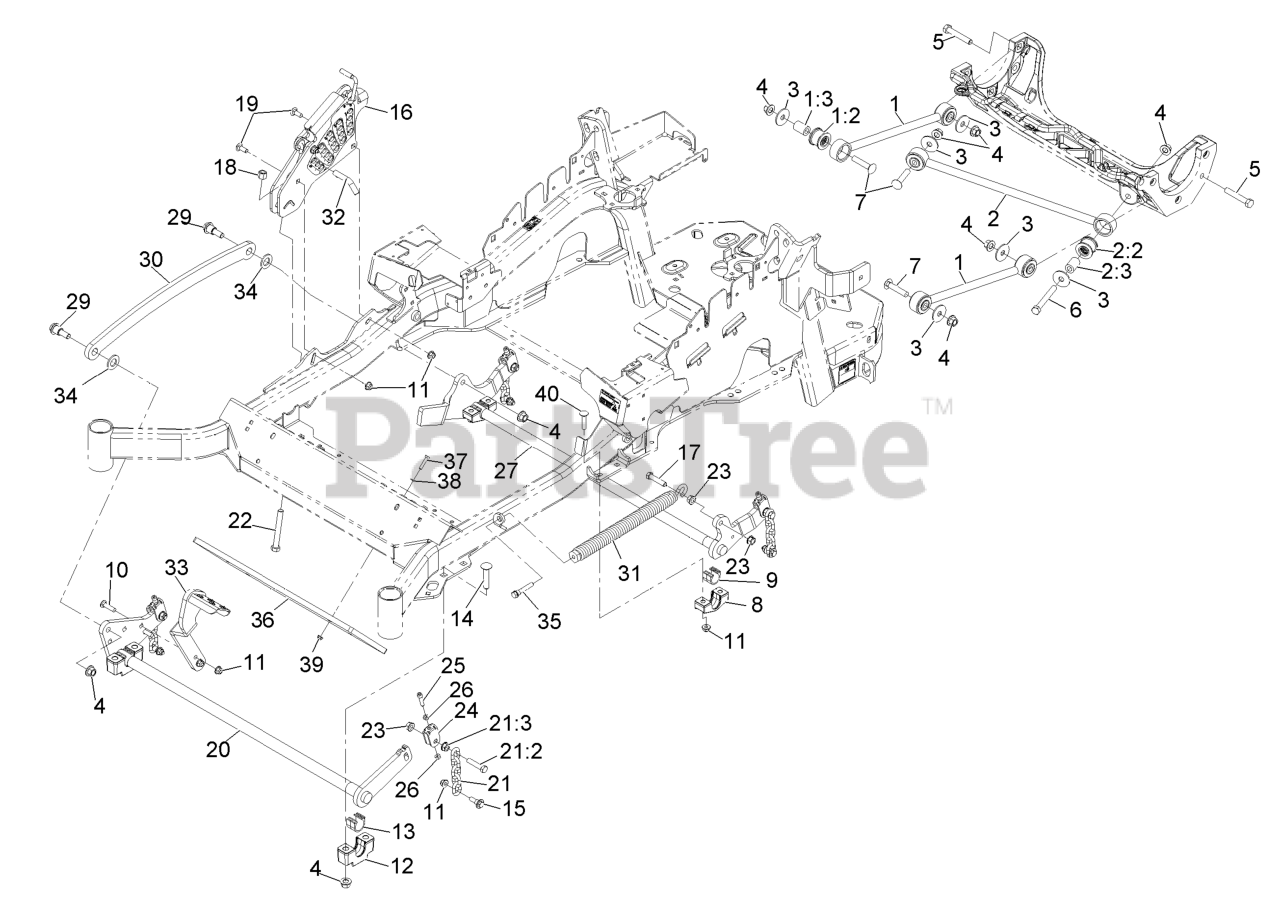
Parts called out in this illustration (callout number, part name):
1	DECK STRUT ASM
1:2	BUSHING-SUSPENSION, RUBBER
2	PANHARD ROD ASM
2:2	BUSHING-SUSPENSION, RUBBER
3	WASHER-THRUST
4	Nut-Lock 1/2-13
5	SCREW-HH
6	SCREW-HH
7	SCREW-CARR
9	BEARING-CROSS SHAFT, REAR
10	SCREW-CARR
11	NUT-HF, NI
12	SUPPORT-CROSS SHAFT, BEARING
13	BEARING-CROSS SHAFT, FRON
14	Bolt-Carriage 1/2-13 X 2 1/2 Spl Neck
15	SCREW-SHOULDER, HHF
16	HOC ASM
17	SCREW-HH
18	NUT-LOCK, NI
19	BOLT-CARR
21	DECK LIFT CHAIN ASM
21:2	SCREW-HH
22	BOLT-TAP
24	YOKE-ADJUST, DECK
25	SCREW-HSH
26	NUT-JAM
27	LIFT-DECK, REAR
29	SCREW-SHOULDER, HHF 1/2-13 X 1.12
30	LINK-LIFT, DECK
31	SPRING-EXTENSION
32	PIN-HOC
33	LEVER-FOOT
34	WASHER-FLAT
35	BOLT-SHOULDER
36	WEIGHT,TOE BOARD
37	SCREW-HH
38	WASHER-FLAT
40	SCREW-CARR
